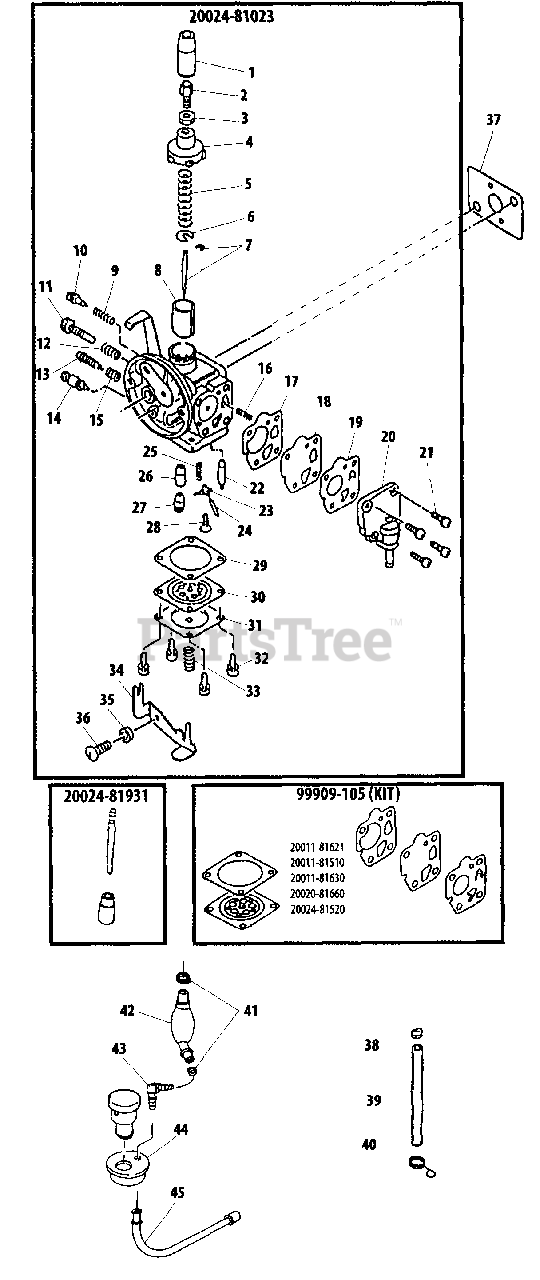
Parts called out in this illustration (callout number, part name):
1	GROMMET
2	NUT, CABLE ADJUST
3	LOCKNUT
4	CAP, CARBURETOR
5	SPRING
6	RETAINER
7	JET NEEDLE KIT
8	VALVE, THROTTLE
9	SPRING
10	SCREW, SLOW AIR
11	SCREW, IDLE ADJUST
12	SPRING
13	SCREW, IDLE ADJUST
14	VALVE, OVERFLOW
15	SCREW, IDLE ADJUST
16	SPRING
17	GASKET, METERING
18	DIAPHRAGM, METERING
19	VALVE, PUMP
20	BODY, PUMP
21	SCREW
22	VALVE, INLET NEEDLE
23	LEVER, METERING
24	PIN, METERING LEVER
25	SPRING
26	JET NEEDLE KIT
27	HOLDER, JET
28	SCREW, METERING LEVER PIN
29	GASKET
30	DIAPHRAGM
31	COVER, DIAPHRAGM
32	SCREW
33	SPRING
34	LEVER, TICKLER
35	COLLAR
36	SCREW
37	GASKET, INTAKE
38	RING, RETAINING - 6
39	PIPE
40	HOLDER, PIPE
41	RING, RETAINING
42	PIPE - FUEL
43	JOINT
44	GROMMET
45	PIPE - FUEL
20024-81023	CARBURETOR
20024-81931	JET NEEDLE KIT
99909-105	DIAPHRAGM/GASKET KIT
